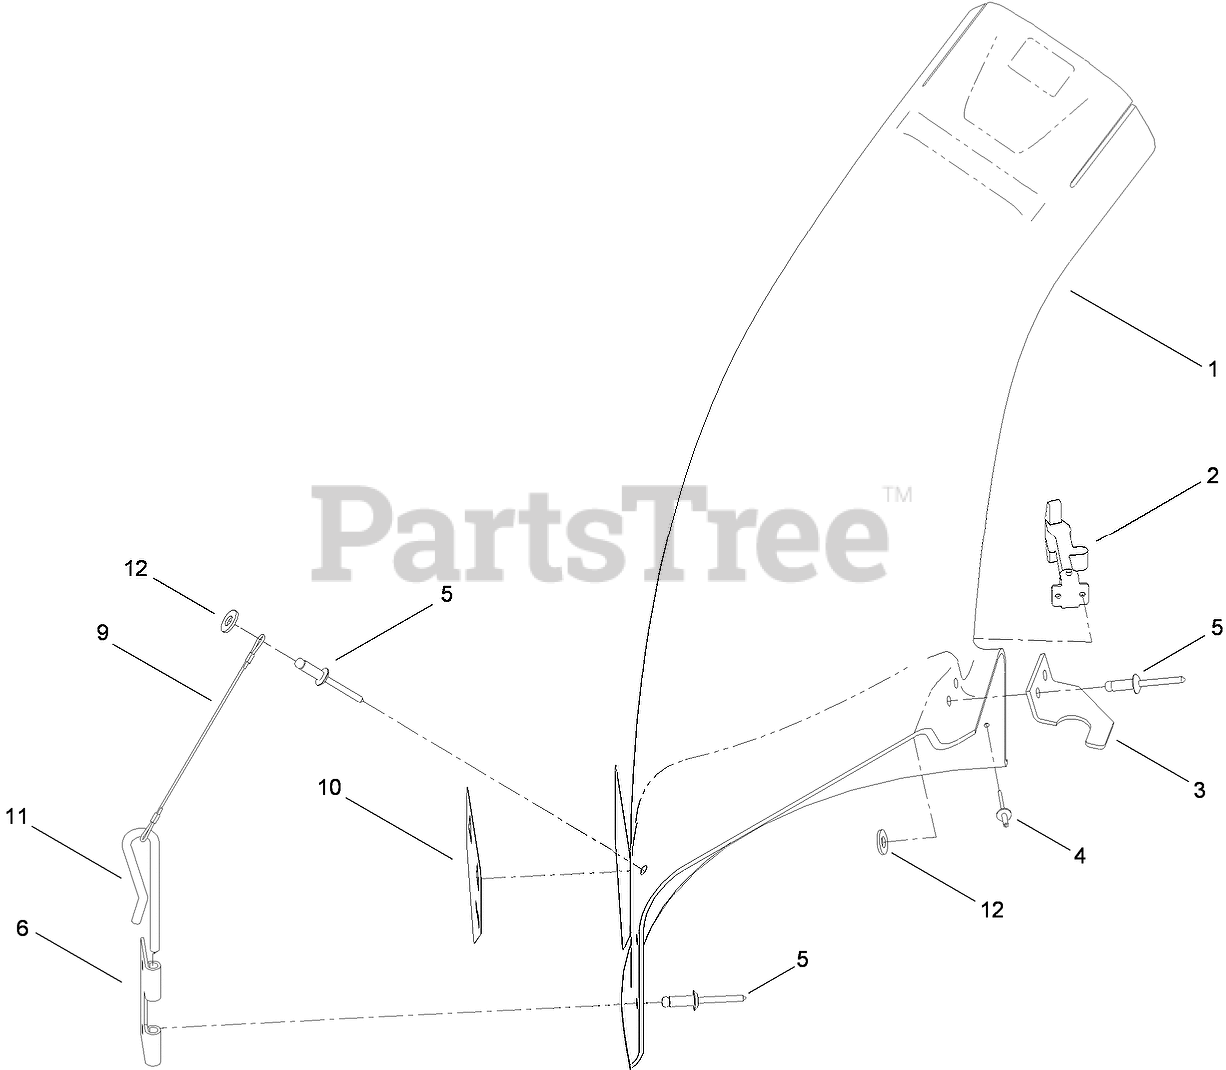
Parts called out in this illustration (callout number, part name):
1	ELBOW-BAGGER, 38 INCH
2	HANDLE ASM
3	LATCH-ELBOW, BAGGER
4	RIVET-POP
5	RIVET-BLIND
6	BRACKET-MOUNTING, CHUTE
9	LANYARD
10	DECAL-DANGER, CE
11	PIN-LOCKING, CHUTE
12	WASHER-FLAT
